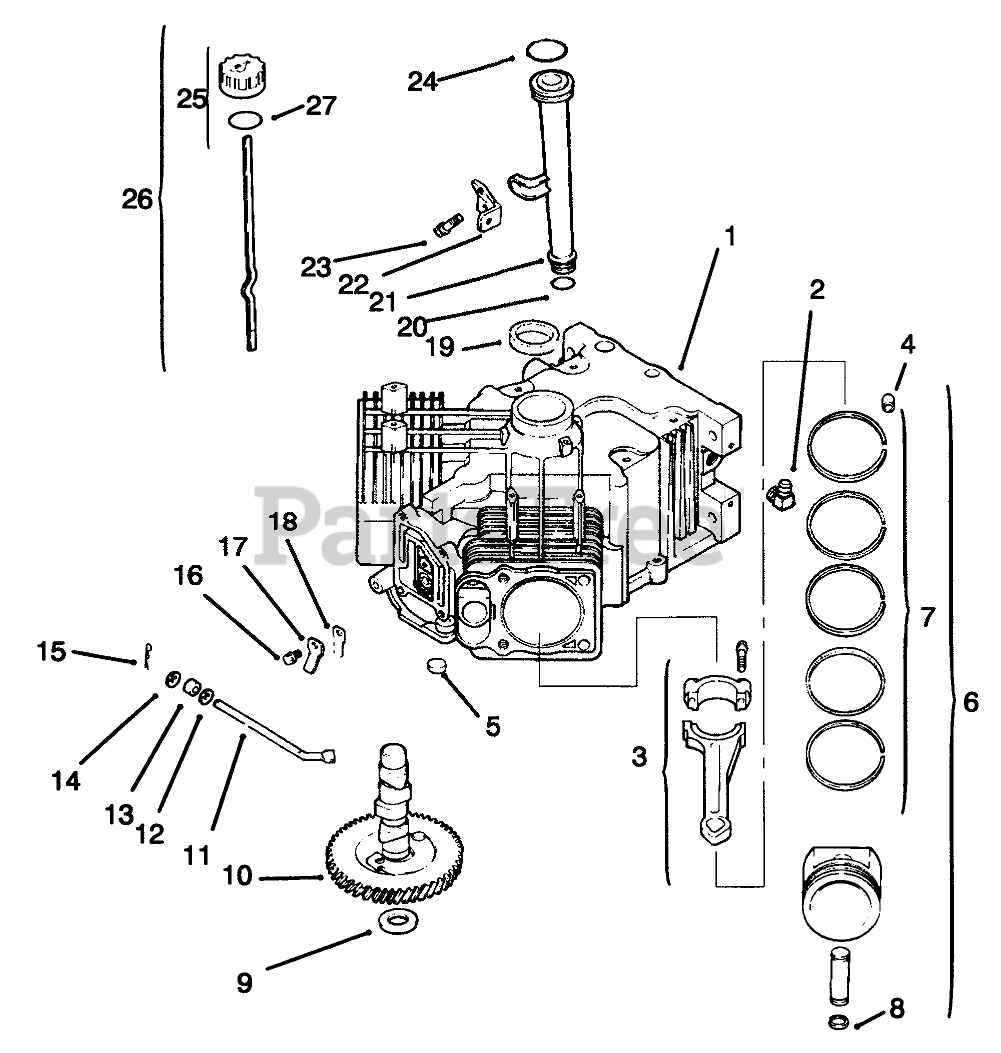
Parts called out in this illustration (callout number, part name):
1	Short Block
2	Connector
3	Connecting Rod STD
3	Connecting Rod .25
4	Pin-Dowel
5	Plug
6	Piston ASM STD INC4/7/8
6	Set-Piston w/Ring .25
6	Piston ASM .50 INC4/7/8
7	Ring Set(Std.)
7	Set-Ring .25
7	Set-Ring .50
8	Retainer-Piston Pin
9	Shim-Camshaft
10	Camshaft
11	Shaft-Governor Cross
12	Washer-Flat
13	Seal-Cross Shaft
14	Washer
15	Pin-Hitch
16	Screw
17	Retainer-Reed
18	Beed-Breather
19	Seal-Oil
20	"O"Ring
21	Tube-Oil Fill
22	Bracket-Oil Tube
23	Screw-HF
24	"O"Ring
25	Dipstick INC 26-27
26	Kit-Oil Fill Cap
27	"O"Ring
